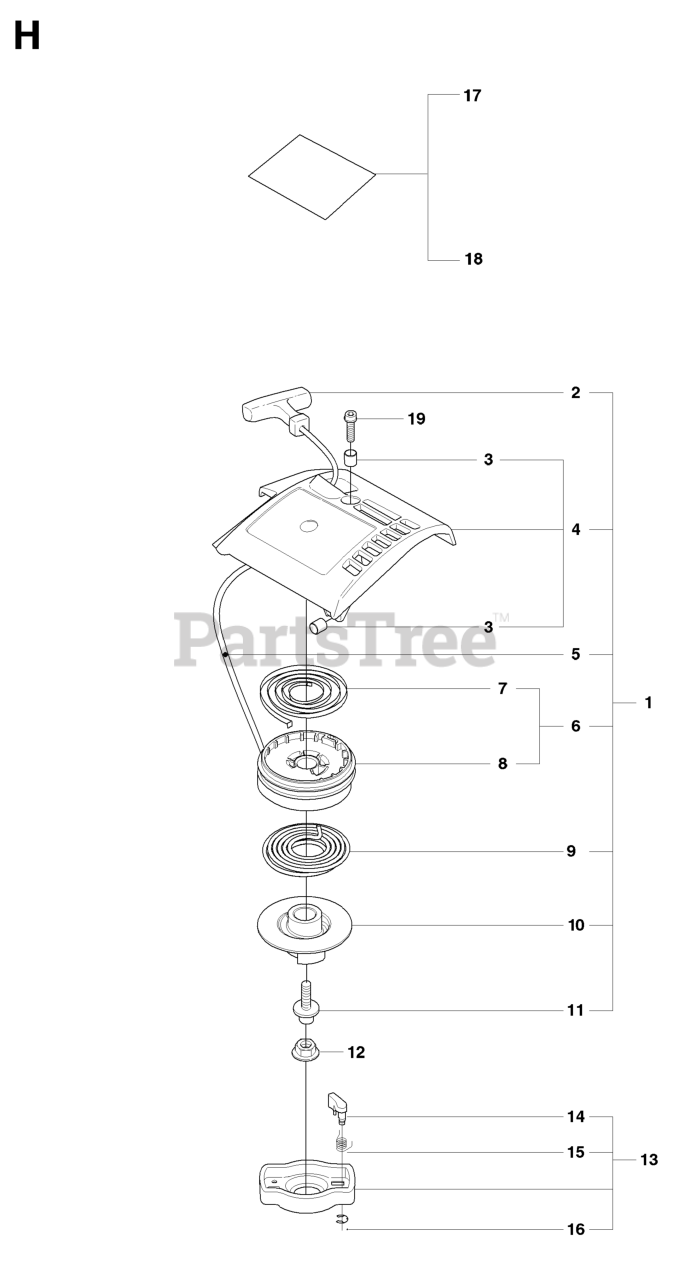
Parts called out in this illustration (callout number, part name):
1	RP STARTER ASSY
2	STARTER HANDLE
3	SPACING SLEEVE
4	STARTER HOUSING
5	STARTER ROPE
6	STARTER PULLEY
8	STARTER PULLEY
9	SPRING - DRIVER
10	DRIVER PULLEY
12	FLANGE NUT
13	PAWL ASSY COMPLETE
14	STARTER PAWL
